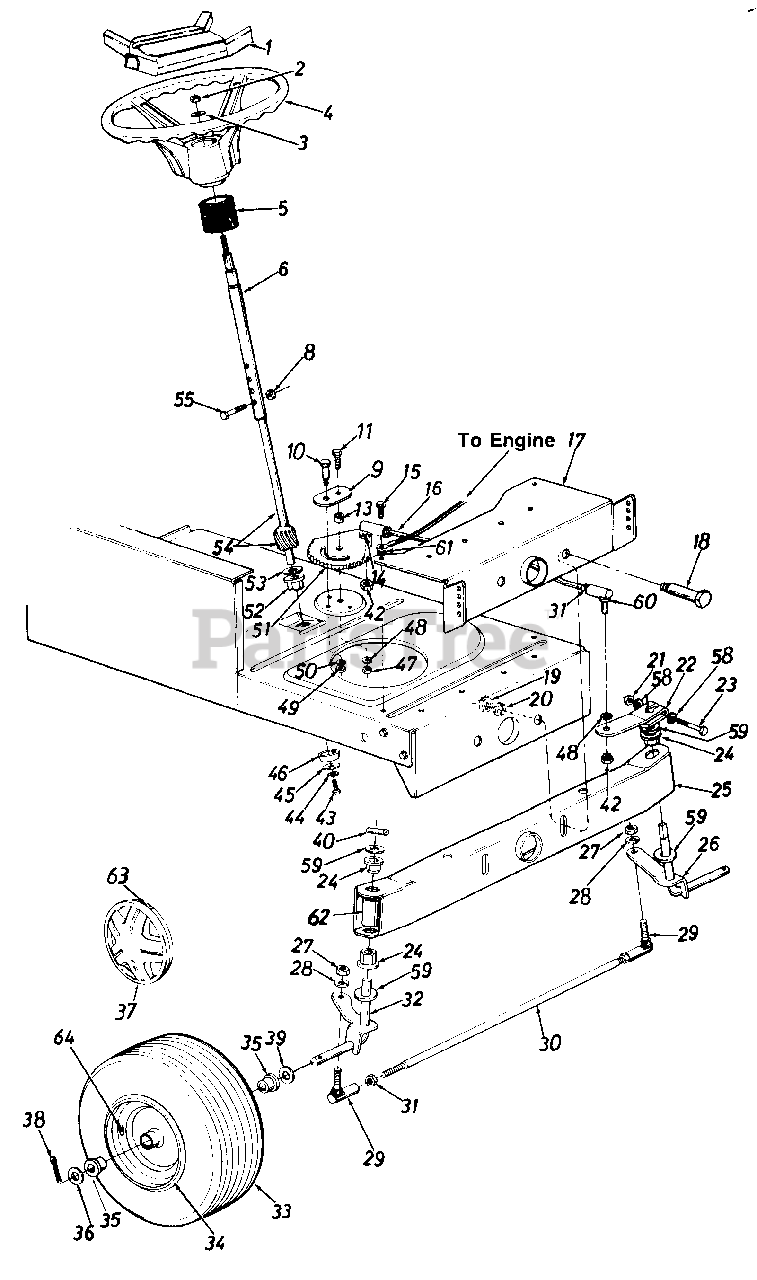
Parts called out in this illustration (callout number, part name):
1	Steering Wheel Insert
2	Hex L-Nut 5/16-24 Thd.
3	Belleville Wash. .345" I.D.
4	Steering Wheel
5	Steering Bellow
6	Steering Column Ass'y.
8	Hex L-Nut 1/4-20 Thd.
9	Retainer Plate
10	Shoulder Bolt .437" Dia. x .35 Lg. 5/16-18 Thd.
11	Hex Bolt 3/8-24 x 1.0" Lg. (Grade 5)
13	Spacer .380" I.D. x.625" O.D. x .227
14	L-Wash. 3/8" I.D.
15	Hex Wash. Hd. Self-Tap Scr.
16	Steering Drag Link
17	Front Pivot Brkt.
18	Shoulder Bolt .498" Dia. x 2.04 Lg. 3/8-16 Thd.
19	Hex Nut 3/8-16 Thd.
20	L-Wash. 3/8" I.D.
21	Hex Cent. L-Nut 5/16-24 Thd.
22	Steering Arm Front Axle
23	Hex Bolt 5/16-24 x 2.00" Lg. (Grade 5)
24	Hex Flg. Brg. .634 I.D.
26	Front Axle Ass'y. L.H.
27	Hex Nut 3/8-24 Thd.
28	L-Wash. 3/8" I.D.
29	Ball Joint 3/8-24 Thd.
30	Tie Rod
31	Hex Jam Nut 3/8-24 Thd.
32	Front Axle Ass'y. R.H.
33	Wheel Ass'y. Comp.
34	Front Wheel Rim Only
35	Bronze Flange Bearing
36	Fl-Wash. .635 I.D. x 1.59" O.D.
37	Front Wheel Hub Cap
38	Cotter Pin 1/8" Dia. x 1.25"
39	Fl-Wash. .640" I.D. x 1.24" O.D.
40	Spring Roll Pin 1.12" Lg.
42	Hex Jam Nut 3/8-24 Thd.
43	Hex L-Bolt 5/16-18 x .62
44	L-Wash. 5/16" I.D.
45	Fl-Wash. .33" I.D. x 1.25" O.D.
46	Spacer (Plastic)
47	Hex Nut 3/8-24 Thd.
48	L-Wash. 3/8" I.D.
49	Hex Nut 5/16-18 Thd.
50	L-Wash. 5/16" I.D.
51	Steering Gear Segment
52	Hex Flg. Brg. .634 I.D.
53	Fl-Wash. (Hardened)
54	Steering Shaft Lower
55	Hex Bolt 1/4-20 x 1.25" Lg.
58	Wave-Wash. .32" I.D. x .62" O.D.
59	Fl-Wash. (Hardened)
60	Drag Link Ball Joint 3/8-24 Thd.
61	Ext. L-Wash. 5/16" I.D.
62	Plastic Tube
63	Spring Clip
64	Air Valve
